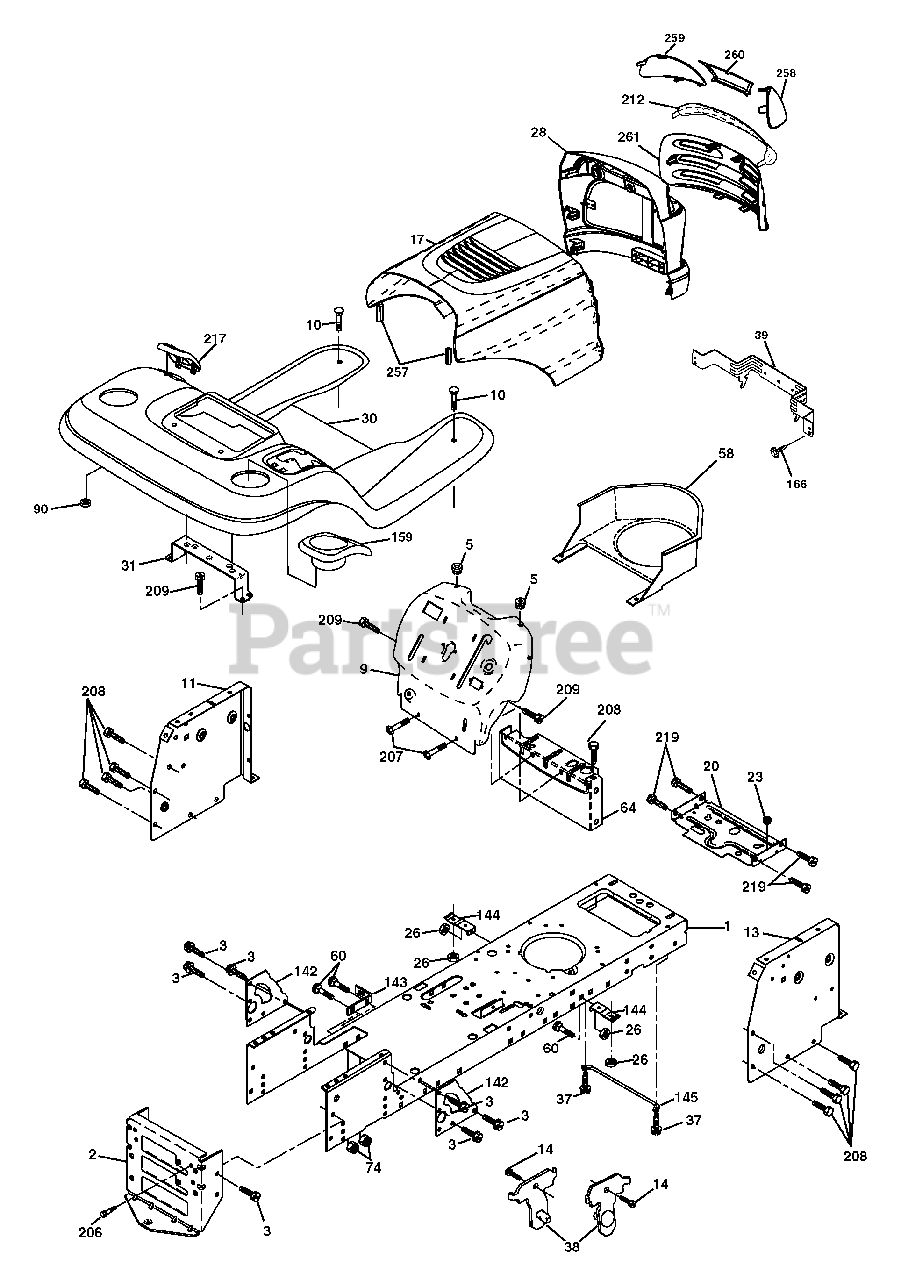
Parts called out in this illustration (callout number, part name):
1	Chassis Stamping
3	Screw 3/8-16 x 3/4
9	Dashboard
10	Bolt Rdhd Sqnk 3/8-16 Unc x 1
11	Panel Dash Lh
13	Panel Dash Rh
14	Screw Thdrol 3/8-16 x 1/2
17	Hood
20	Plate Mtg Battery/Fuel Tank
26	Nut Lock w/Insert 3/8-16 Unc
28	Grille Lens Asm
30	Fender
37	Screw Thdrol 5/16-18 x 1/2
38	Bracket Asm Pivot Mower Rear
39	Bracket Pivot
60	Bolt RDHD SQNK 3/8-16 x 3/4
64	Dash Lower Stlt
74	Nut Crownlock 3/8-16
142	Plate Reinforcement
143	Bracket Swaybar Chassis
144	Bracket Ft Rest
145	Rod Pivot Chassis Hood
159	Cupholder
166	Screw Hw Hd Hi-Lo #13-16 x 3/4
206	Bolt Shoulder 5/16-18 TT
207	Screw Thdrol 5/16-18 x 1/2 TYTT
208	Screw Thdrol 3/8-16 x 1/2 Ty-TT
209	Screw 3/8-16 x 3/4
212	Lens Insert Reflect
217	Console Fuel Window
219	Screw 5/16-18 x 3/4
257	Bumper Hood
258	Lens Husq. Laser LT Clear RH
259	Lens Husq. Laser LT Clear LH
260	Lens Cover
261	Insert Grille
